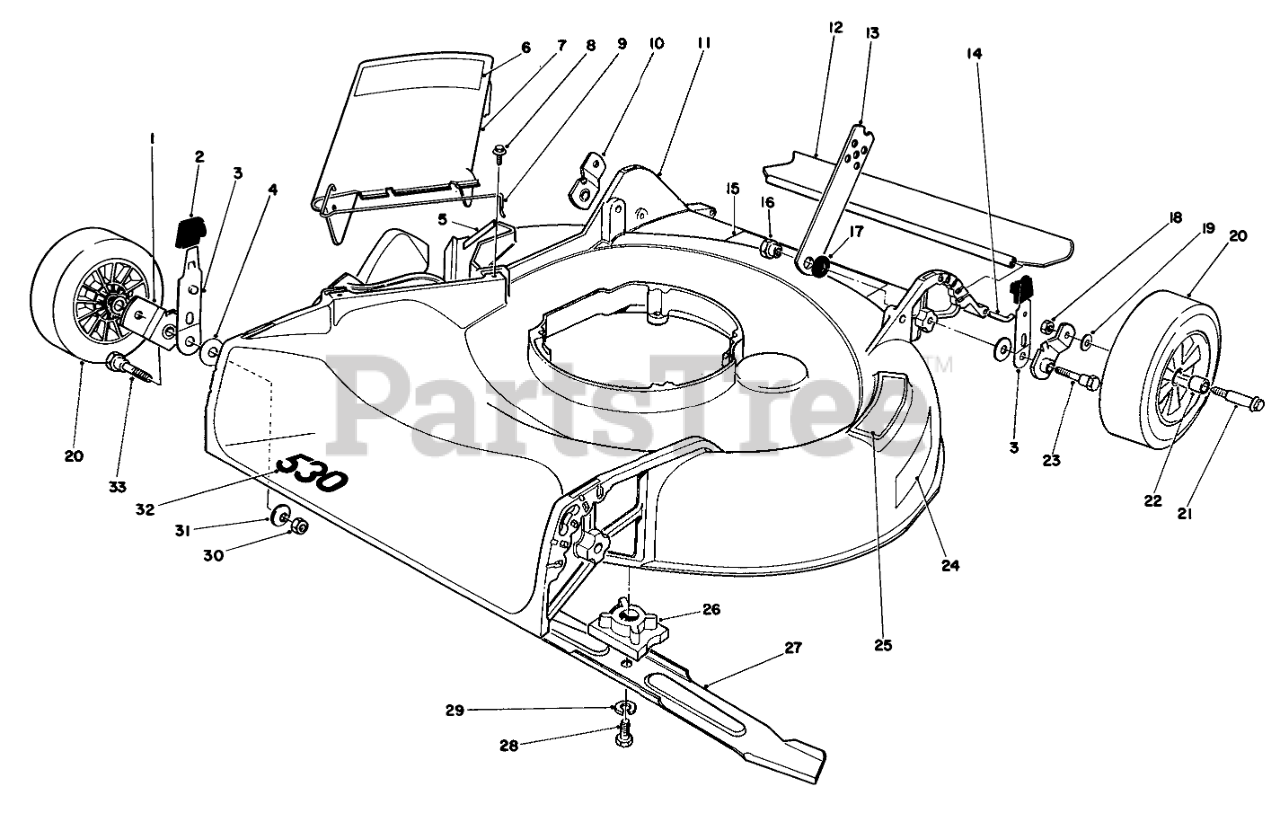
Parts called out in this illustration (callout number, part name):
1	Pivot Arm
2	KNOB-ARM
3	SPRING ARM ASM
4	WASHER-PIVOT
5	Decal-Danger
6	Decal-Danger(French)
7	Deflector Assy. (Incl Ref. #6 &9)
8	SCREW-HWH
9	SPRING HINGE
10	Pivot Arm
11	HOUSING/DECAL
12	REAR SAFETY SHIELD 21
13	HANDLE LATCH
14	SHIELD ROD
15	Danger-Decal
16	HANDLE PIVOT NUT
17	SPACER
18	NUT-LOCK
19	WASHER
20	Wheel & Tire Assembly (Incl. Ref. #22)
21	WHEEL BOLT
22	BUSHING
23	PIVOT SCREW
24	Decal-Step
25	STEP PAD DECAL
26	BLADE RETAINER
27	Blade
28	SCREW-HH
29	WASHER-LOCK
30	NUT-LOCK, NI
31	WASHER-BELLEVILLE
32	Decal-530
33	PIVOT SCREW
